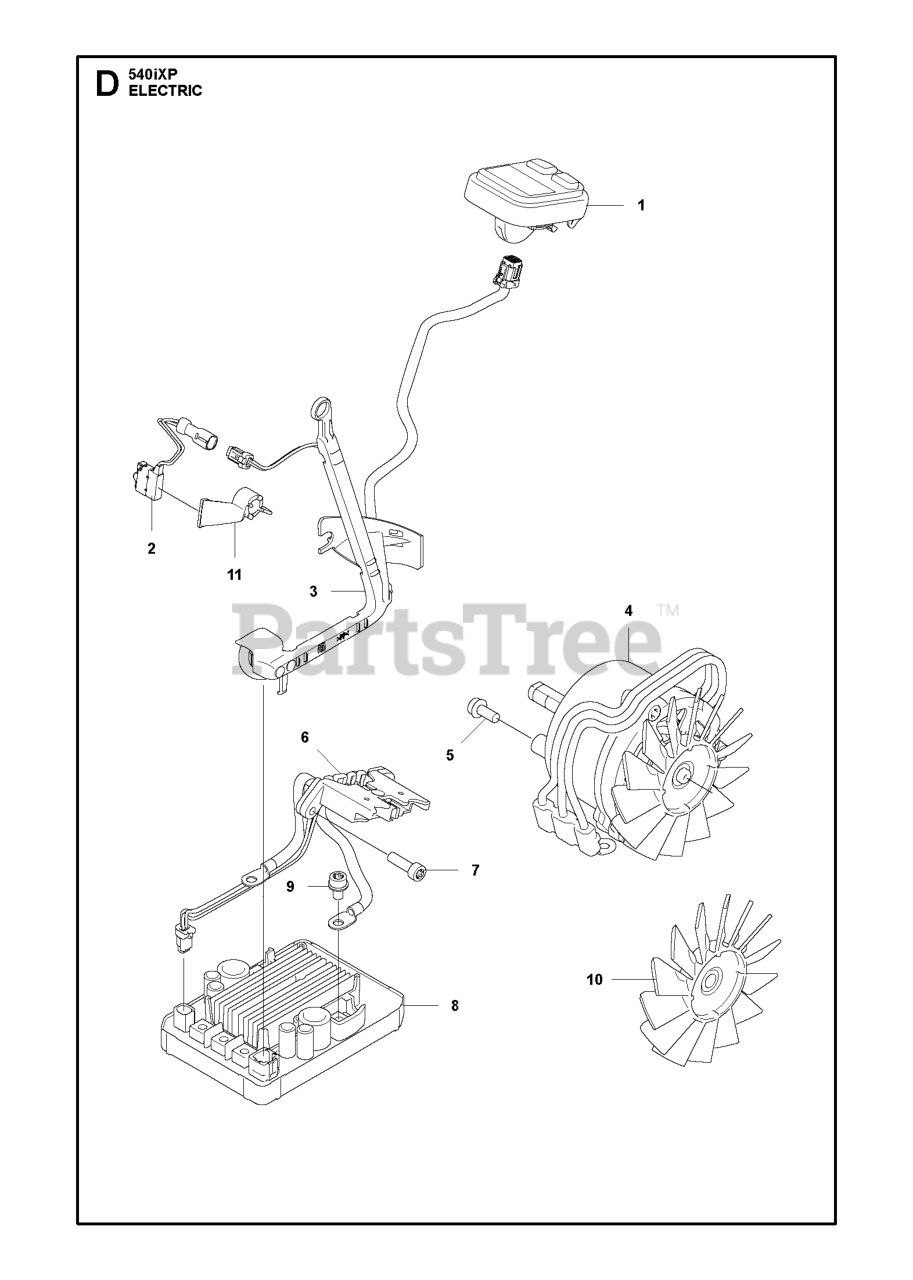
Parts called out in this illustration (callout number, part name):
1	Control Panels
3	Wiring Harness
5	SCREW
6	Wiring Harness
7	SCREW ITXSCT PW4.2X18 10.9 ZN
8	CONTROL UNIT
9	SCREW ITXSCFM M5X8 T27 10.9 Z
